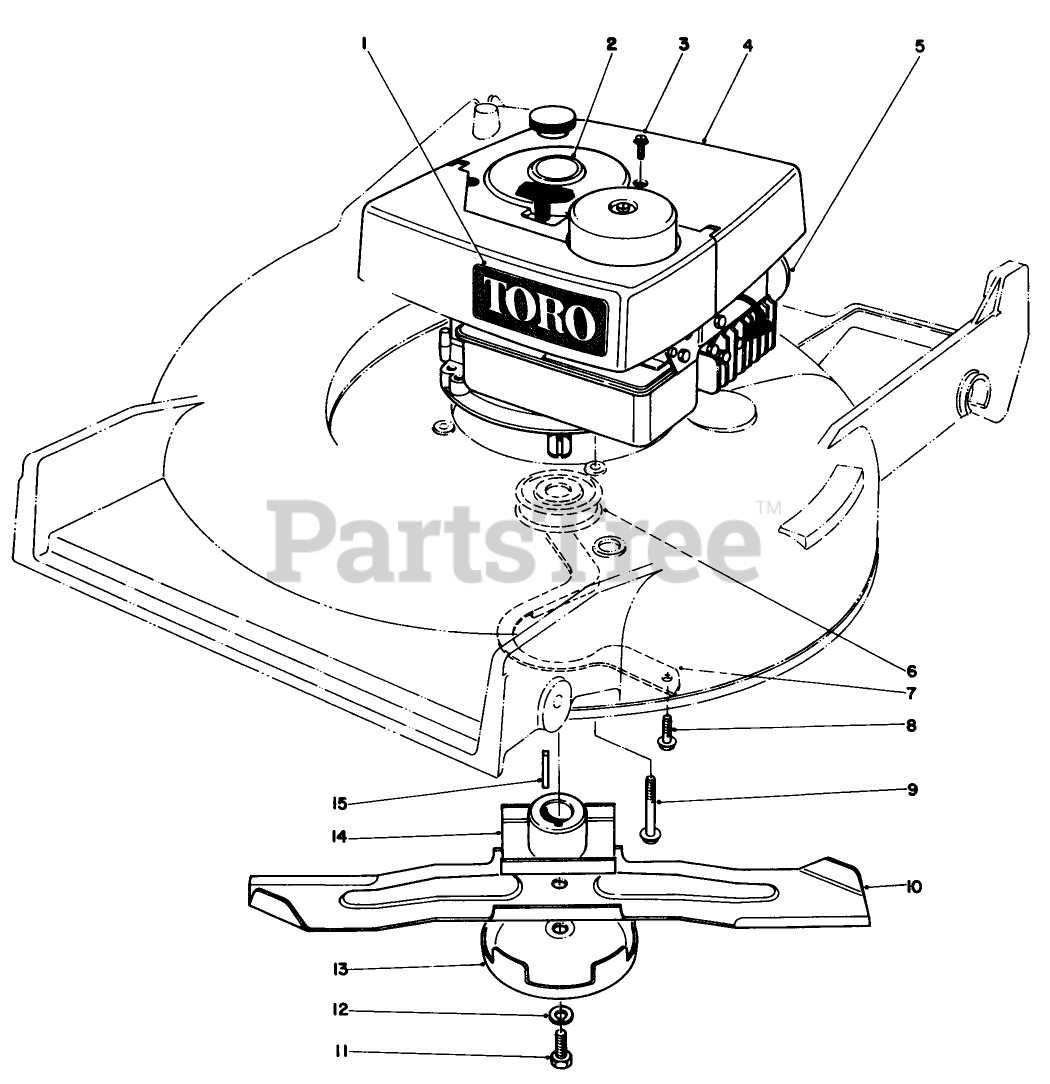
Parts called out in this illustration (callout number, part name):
1	Decal Tow
2	Decal-Shroud
3	TAPPING SCREW
4	SHROUD
5	Engine
6	DRIVER PULLEY
7	BELT GUIDE
8	Screw
9	SCREW-HWHTF
10	Blade
11	SCREW-BLADE
12	WASHER-LOCK
13	AntiScalp Cup
14	Blade Retainer
15	KEY-SQUARE
